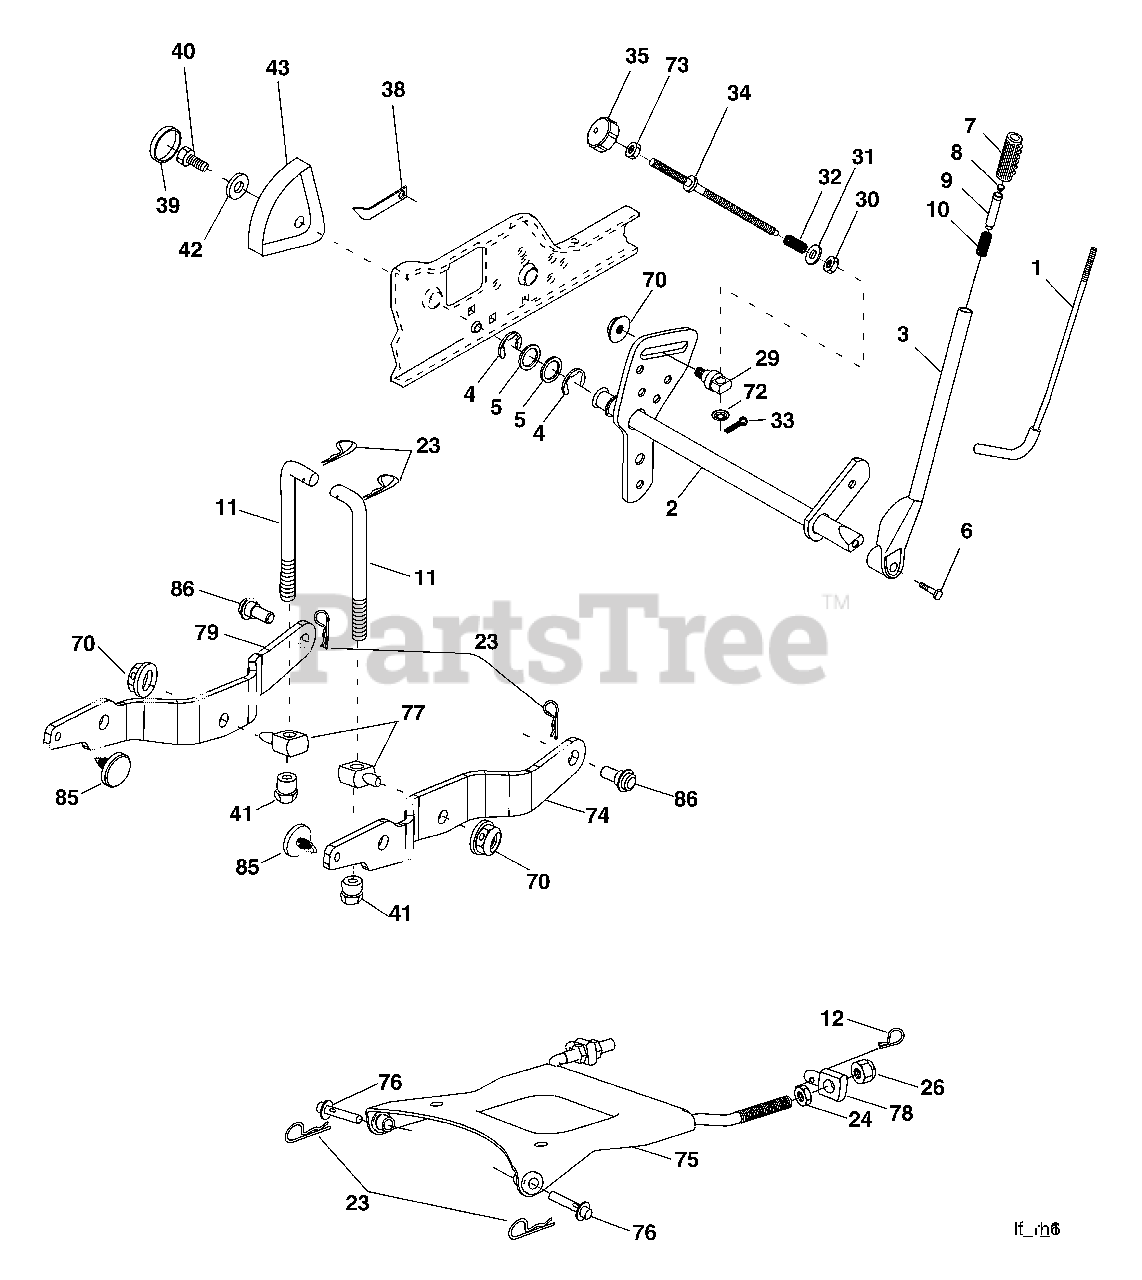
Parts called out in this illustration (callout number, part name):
1	Rod Asm., Lever
2	Shaft Asm., Lift Vgt
3	Lever Asm., Lift Rh
4	E-Ring Truarc #5133-87
5	Washer 29/32 x 1-1/4 x 16 Ga.
6	Bolt, Fin Hex 3/8-16 x 1-1/2
7	Grip, Handle
8	Button, Plunger
9	Plunger, Lever Lift
10	Spring 0.620D x 2.125
11	Link Lift
12	Retainer, Spring
23	Retainer, Spring
24	Nut, Jam Hex 1/2-13 unc
26	Nut, Lock W/Wsh 1/2-13 unc
29	Trunnion Infi n Height
30	Nut, Special
31	Washer 13/32 x 5/8 x 16 Ga.
32	Spring, Compression Inf Hgt
33	Pin, Cotter 3/32 x 1/2
34	Rod, Adj Lift
35	Knob, Inf 3/8-16 unc
38	Pointer Height Indicator
39	Plug, Hole Blk. 1.485/1.515 Dia.
40	Screw 5/16-18 x 1
41	Nut, Lift Link 7/16-20
42	Washer 11/32 x 1-1/2 x 10 Ga.
43	Scale, Indicator Height
70	Nut Hex Flange Lock
72	Nut Push Phos & Oil
73	Nut, Hex Jam 3/8-16 unc
74	Arm Suspension Rear RH
75	Plate, Asm, Susp, Front
76	Pin Flange
77	Trunion Susp Arm
78	Trunnion, Front, Susp
79	Arm, Suspension LH
85	Insert Wear
86	Bolt Shoulder
